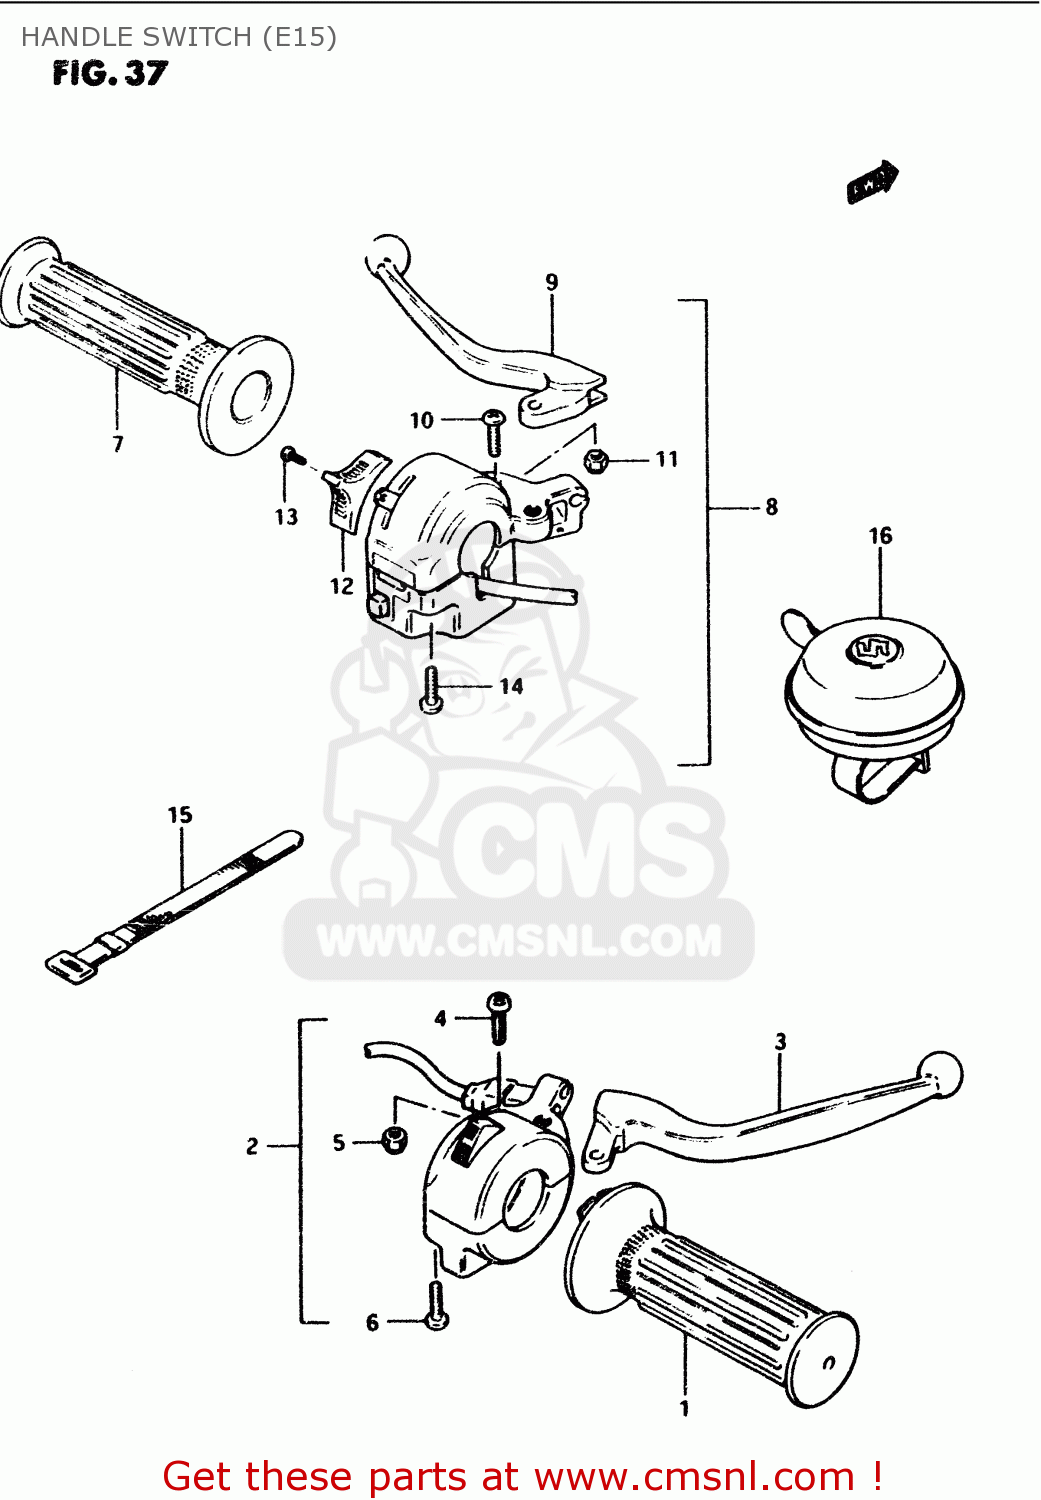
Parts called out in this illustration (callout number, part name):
1	GRIP,THROTTLE
2	BRAKE LEVER & SWITCH ASSY
3	LEVER
4	BOLT,LEVER PIVOT
5	NUT
6	SCREW
7	GRIP,L
8	CLUTCH LEVER & SWITCH ASSY
9	LEVER
10	BOLT,LEVER PIVOT
11	NUT
12	KNOB
13	SCREW,KNOB
14	SCREW
15	CLAMP(L:120)
16	BELL ASSY
